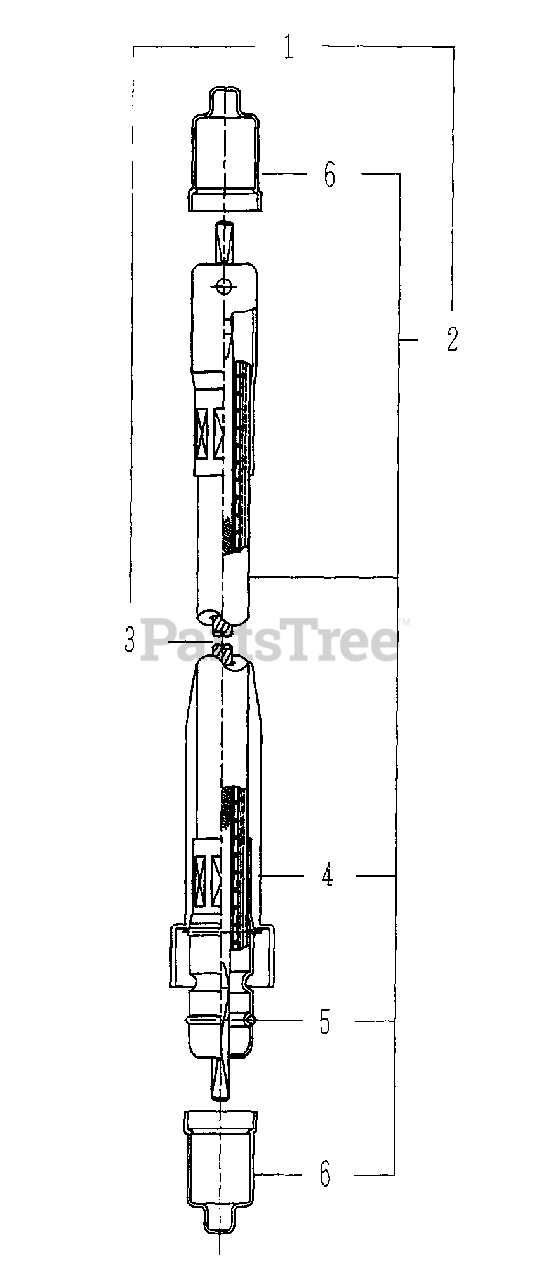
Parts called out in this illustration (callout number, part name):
1	TUBE ASSY W/SHAFT, FLEX
2	TUBE ASSY, FLEX
3	DRIVESHAFT - FLEXIBLE
4	TUBE, FLEXIBLE
5	O-RING
6	CAP
